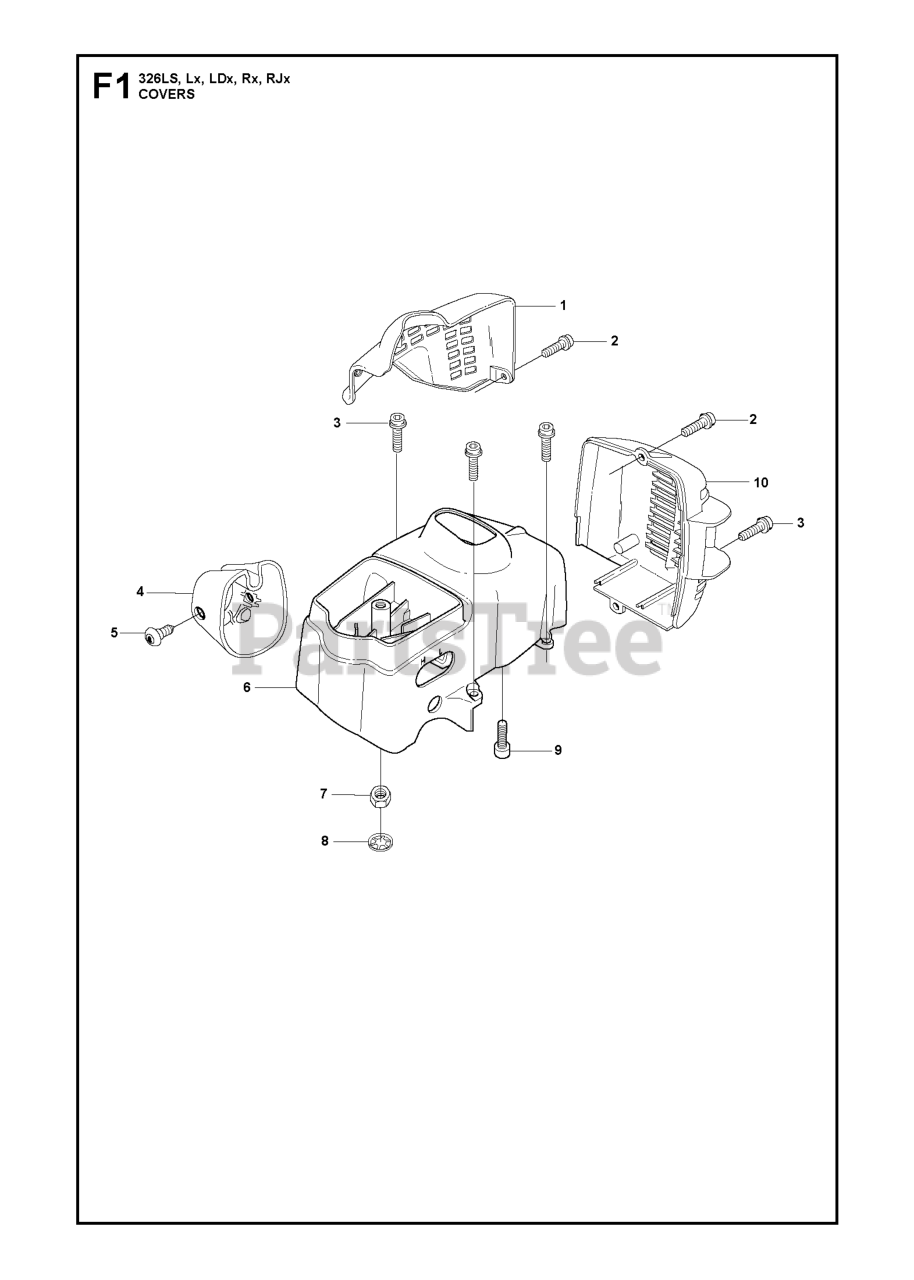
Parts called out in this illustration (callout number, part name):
1	HEAT PROTECTOR, CYLINDER
2	SCREW
3	SCREW
4	COVER
5	SCREW MT5X11
6	CYLINDER COVER
9	SCREW
10	GUARD MUFFLER
